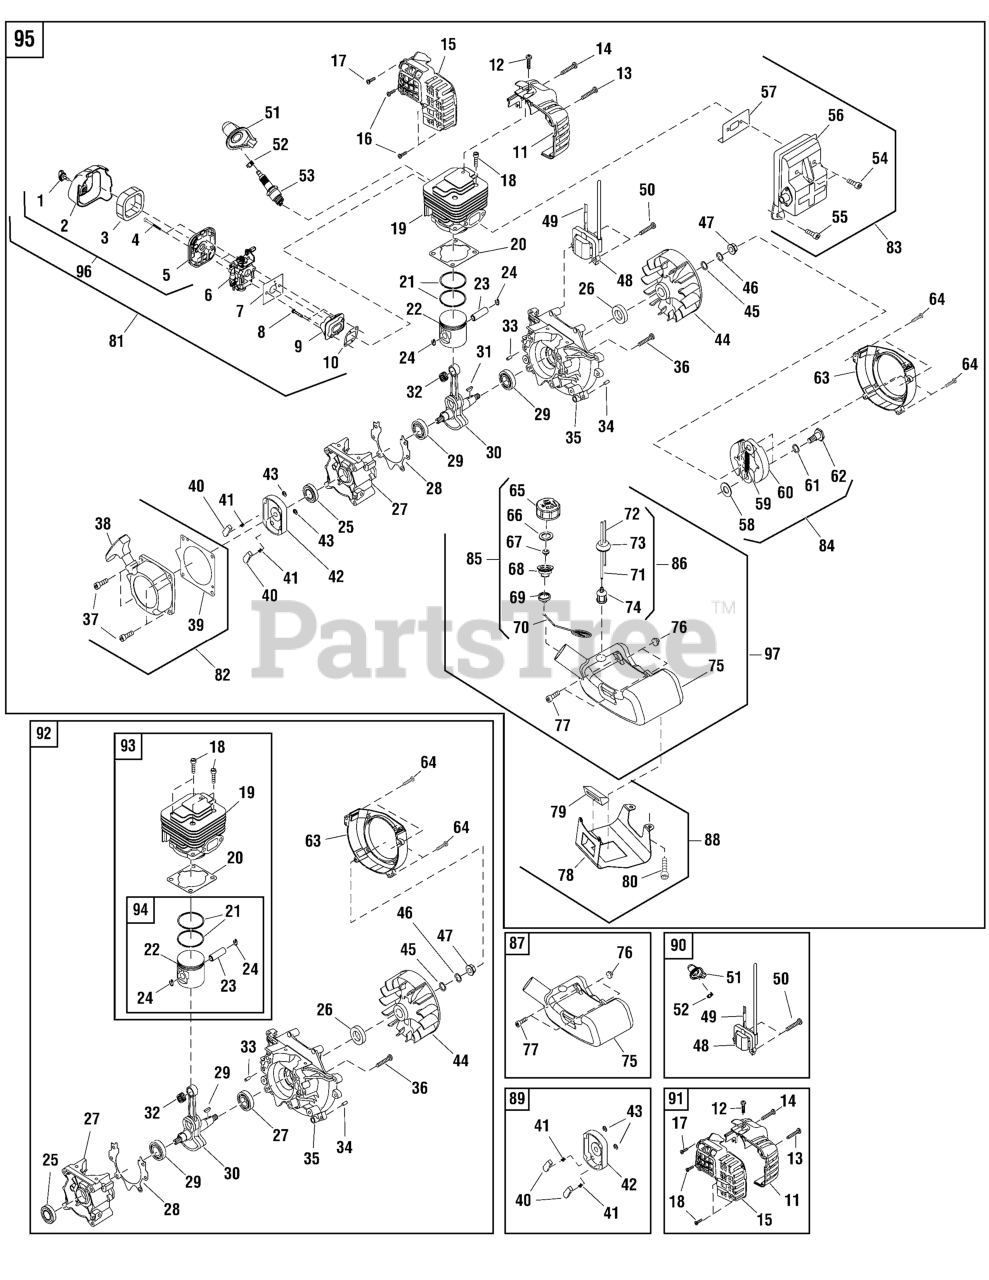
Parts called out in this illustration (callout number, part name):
2	COVER, Cleaner, Outer
3	FILTER
4	BOLT, M5 x 55
5	COVER, Cleaner, Inner
6	CARBURETOR
7	GASKET, Carburetor
8	BOLT, M5 x 25
9	ADMITTING PIPE
10	GASKET, Admitting Pipe
11	SHROUD, Front
15	SHROUD, Rear
16	SCREW, Self Tapping, ST5 x 20
17	SCREW, Self Tapping, ST4.2 x 25
18	BOLT, M5 x 20
19	CYLINDER HEAD
20	GASKET, Cylinder Head
21	PISOTN RING
22	PISTON
23	PIN, Piston
24	RING, Pin Retain
25	OIL SEAL,11.7 x 22 x 7
26	OIL SEAL, 30 x 14.7 x 7
27	CRANK CASE, Rear
28	GASKET, Crank Case
29	BEARING, 6201/P6
30	CRANK SHAFT
31	KEY, 3 x 5 x 13
32	NEEDLE BEARING
33	PIN, Cylindrical, B5 x 12
34	PIN, Cylindrical, B4 x 10
35	CRANK CASE, Front
38	KIT, Shroud Assembly
39	PAD, Starter
40	CINCH, Starter
41	SPRING, Starter
42	STARTER BOX
43	RING, Retainer
44	FLY WHEEL
45	WASHER, Flat, 8
46	WASHER, Spring, 8
47	NUT, Hex, M8
48	MAGNETO COIL
49	CORD, Magneto
51	BOOT, Spark Plug
52	CLIP, Spark Plug
53	SPARK PLUG
54	BOLT M6 x 5-10.9
56	MUFFLER
57	GASKET, Muffler
58	WASHER, B
59	SPRING, Clutch
60	EXPANDER, Complete
61	WASHER, Wave
62	SCREW, Shaft
63	COVER, Fan
64	BOLT, M5 x 25
65	LID, Fuel Tank
66	GASKET
67	INLET
68	LID, Fuel Tank, Inner
69	COVER, End
70	CHAIN, Fuel Cap
71	PIPE, Fuel
72	PIPE, Soft PVC
73	PLUG, Fuel Line
74	FILTER, Fuel
75	FUEL TANK
76	PLUG, Rubber
78	BRACKET, Tank
79	COVER, Rubber
81	KIT, Air Cleaner & Carburetor
82	KIT, Starter Assembly
83	KIT, Muffler Assembly
84	KIT, Expander Assembly
85	KIT, Fuel Cap Assembly
86	KIT, Fuel Line Assembly
87	KIT, Fuel Tank Assembly
88	KIT, Tank Bracket Assembly
89	KIT, Start Reel Assembly
90	KIT, Magneto Assembly
91	KIT, Shroud Assembly
92	KIT, Cylinder Assembly
93	KIT, Cylinder Head Assembly
94	KIT, Piston Assembly
95	KIT, Engine, Complete
96	KIT, Air Cleaner
97	KIT, Fuel Tank & Cap
